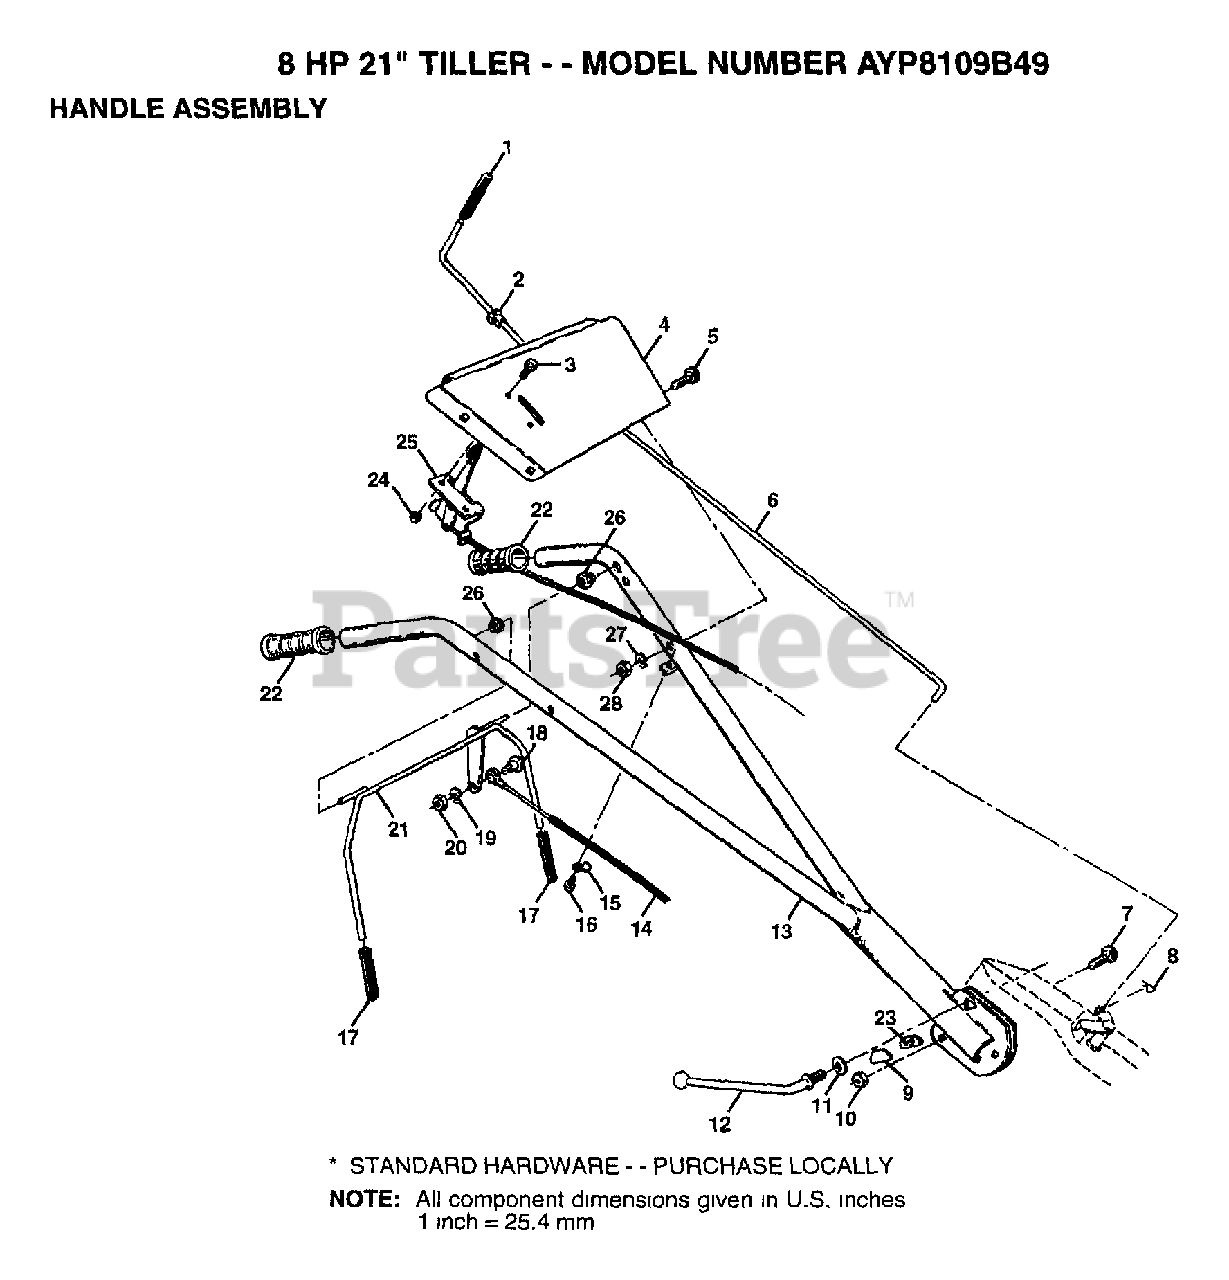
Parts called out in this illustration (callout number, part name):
1	GRIP TI
2	BUSHING
3	SCREW.PNHD.10-24
4	HANDLE BRACKET
5	BOLT CARRIAGE CRT
6	ROD SHIFT CRT
8	RETAINER M
9	LOCK CRT
10	LOCKNUT
11	WASHER CRT
12	LEVER LOCK CRT
14	CABLE-CLUTCH CRT
15	CONDIUT CLIP T
17	GRIP BAR CRT
18	SHOULDER BOLT ST
19	LOCKWASHER
21	HANDLE BAR CRT
22	GRIP HDLE NUBBED
23	LOCK.HANDLE
25	CONTROL.THROTTLE
27	LOCKWASHER
28	NUT
